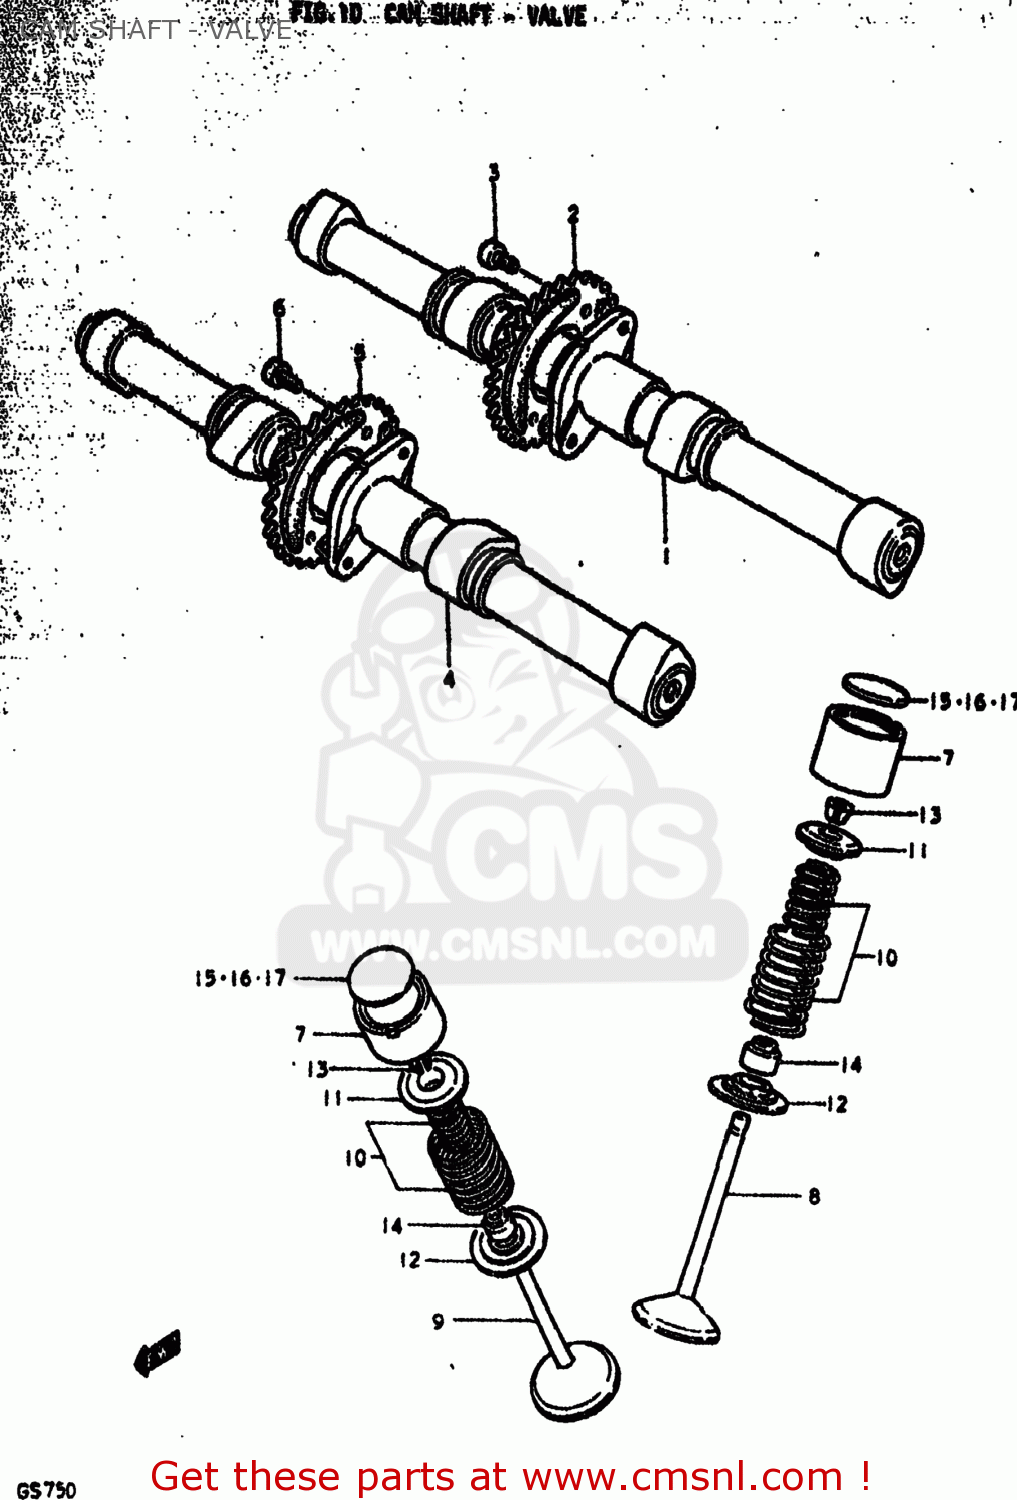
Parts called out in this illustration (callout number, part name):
1	CAMSHAFT
2	SPROCKET,CAMSHAFT
3	BOLT 6X11
4	CAMSHAFT,EXHAUST
5	SPROCKET,EXHAUST CAMSHAFT
6	BOLT 6X11
7	TAPPET
8	VALVE,INTAKE
9	VALVE,EXHAUST
10	SPRING SET,VALVE
11	RETAINER,VALVE SPRING
12	SEAT,VALVE SPRING
13	SHIM,TAPPET
14	SEAL,OIL(7X14.4X9)
15	SHIM,TAPPET
16	SHIM,TAPPET
17	SHIM,TAPPET
18	SHIM SET,TAPPET
19	CASE
